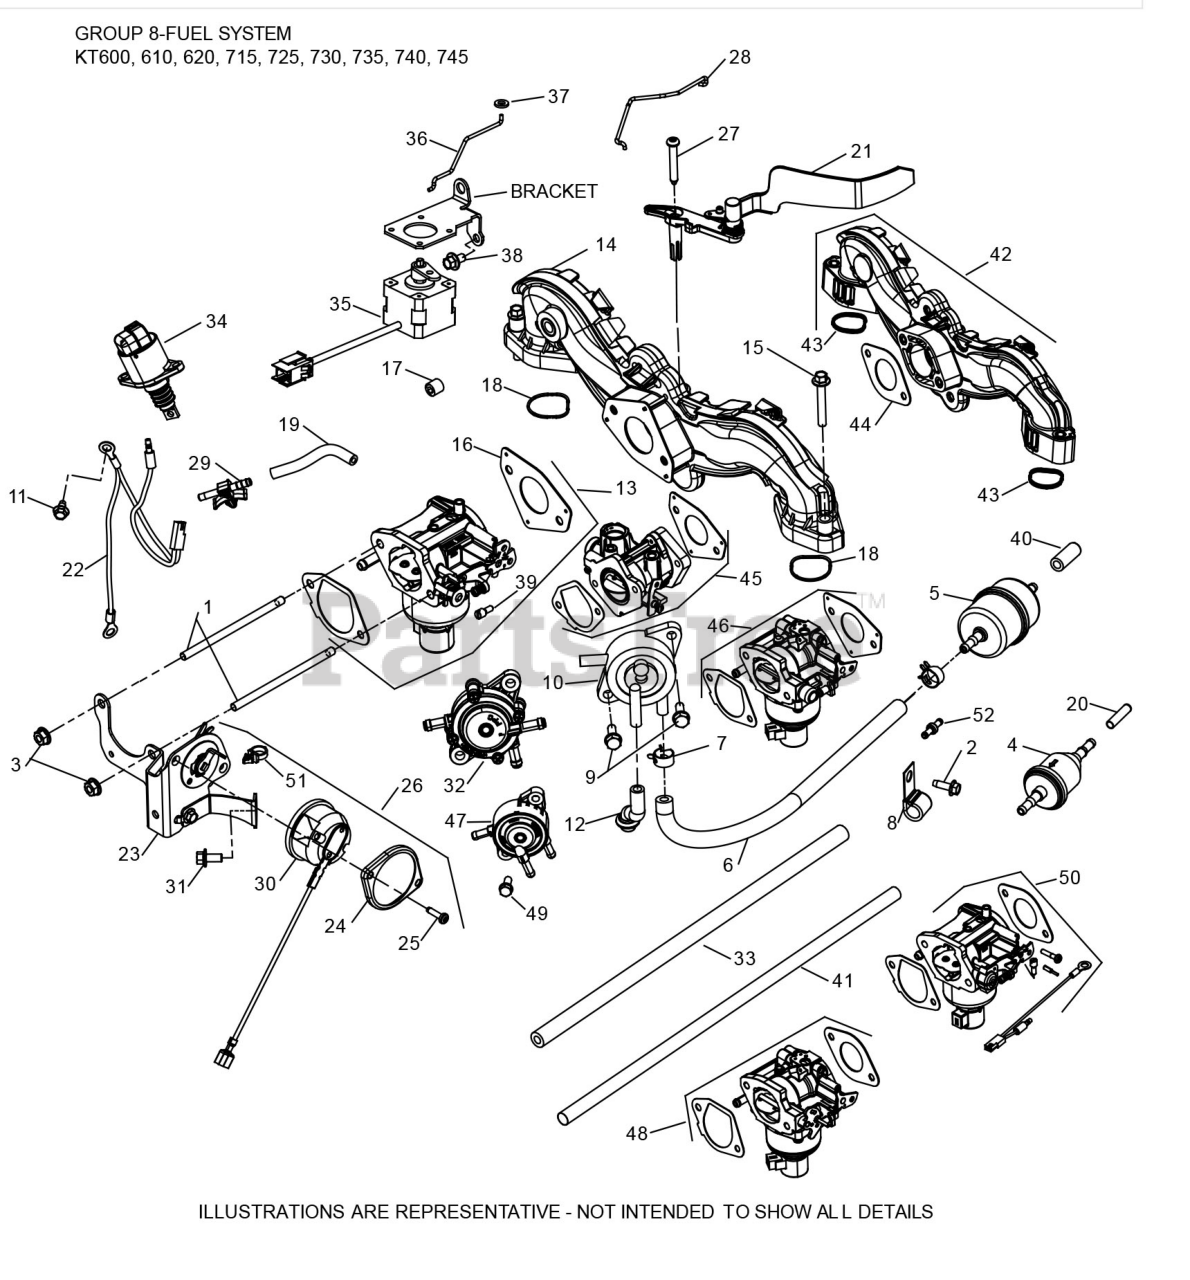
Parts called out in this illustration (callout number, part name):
1	CARB MOUNTING STUD
3	HEX FLANGE NUT
5	FUEL FILTER
15	HEX SCREW FLANGE
19	EVAPORATIVE HOSE
41	SLEEVE-ANTI ABRASION
42	INTAKE MANIFOLD W/GASKETS
43	O-RING, INTAKE PORT
44	GASKET, CARBURETOR (PIM, CV)
49	HEX HEAD SCREW
50	CARBURETOR KIT
